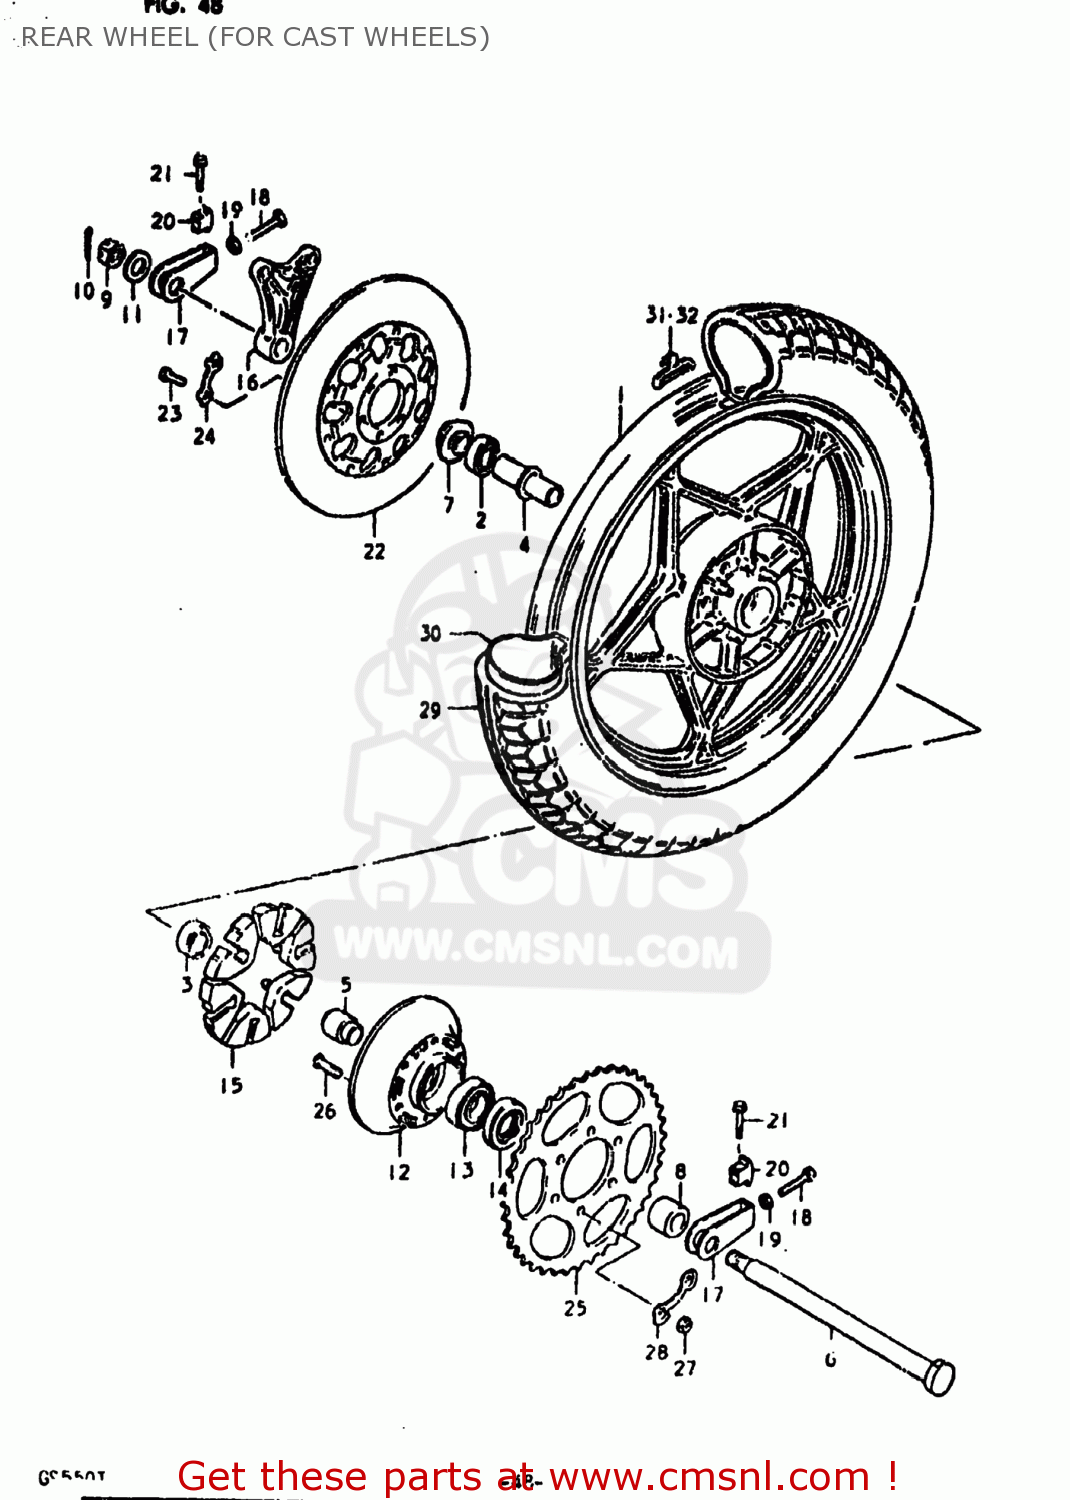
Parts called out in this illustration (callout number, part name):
1	WHEEL, REAR
2	BEARING
3	BEARING
4	SPACER,REAR HUB BEARING
5	RETAINER,REAR SPROCKET D
6	AXLE,REAR
7	SPACER,REAR AXLE
8	SPACER (17X33X21.1)
9	NUT
10	PIN,COTTER
11	WASHER (17X30X3.2)
12	DRUM,REAR SPROCKET MOUNT
13	BEARING
14	SEAL,OIL(33X62X7)
15	ABSORBER,REAR HUB SHOCK
16	BRACKET,RR,CALIPER
17	ADJUSTER,CHAIN
18	BOLT
19	NUT
20	SUPPORTER,CHAIN ADJUST
21	BOLT
22	DISC,BRAKE
23	BOLT(8X30)
24	WASHER
25	SPROCKET,RR
26	BOLT
27	NUT
28	WASHER
29	TIRE
30	TUBE,INNER
31	BALANCER,WHEEL
32	BALANCER,WHEEL
